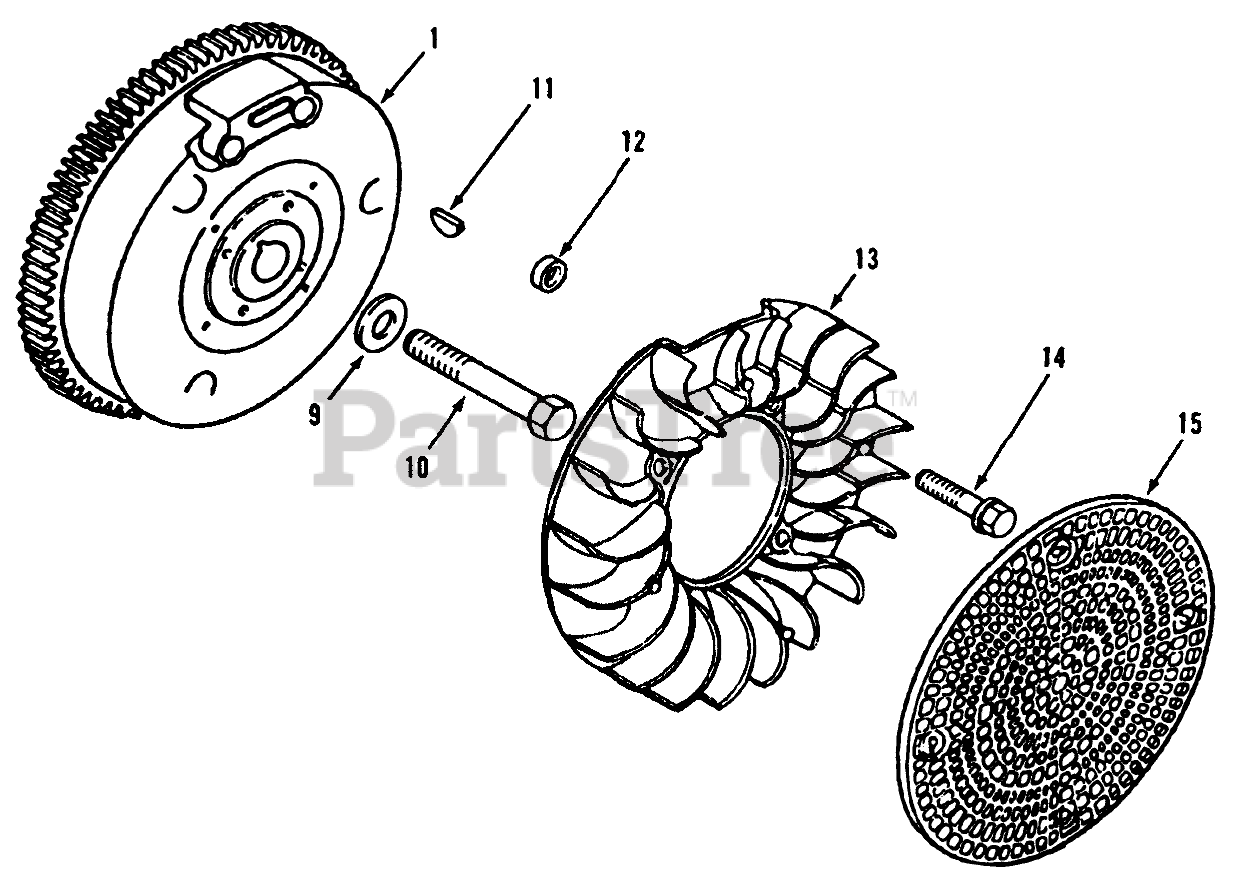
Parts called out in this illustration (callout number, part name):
1	Flywheel
9	Washer
10	Screw
11	Key-Woodruff
12	Spacer 17/64 ID, 3/8 OD 15/64 Lg.
14	Screw-Hex. Hd.
15	Screen
